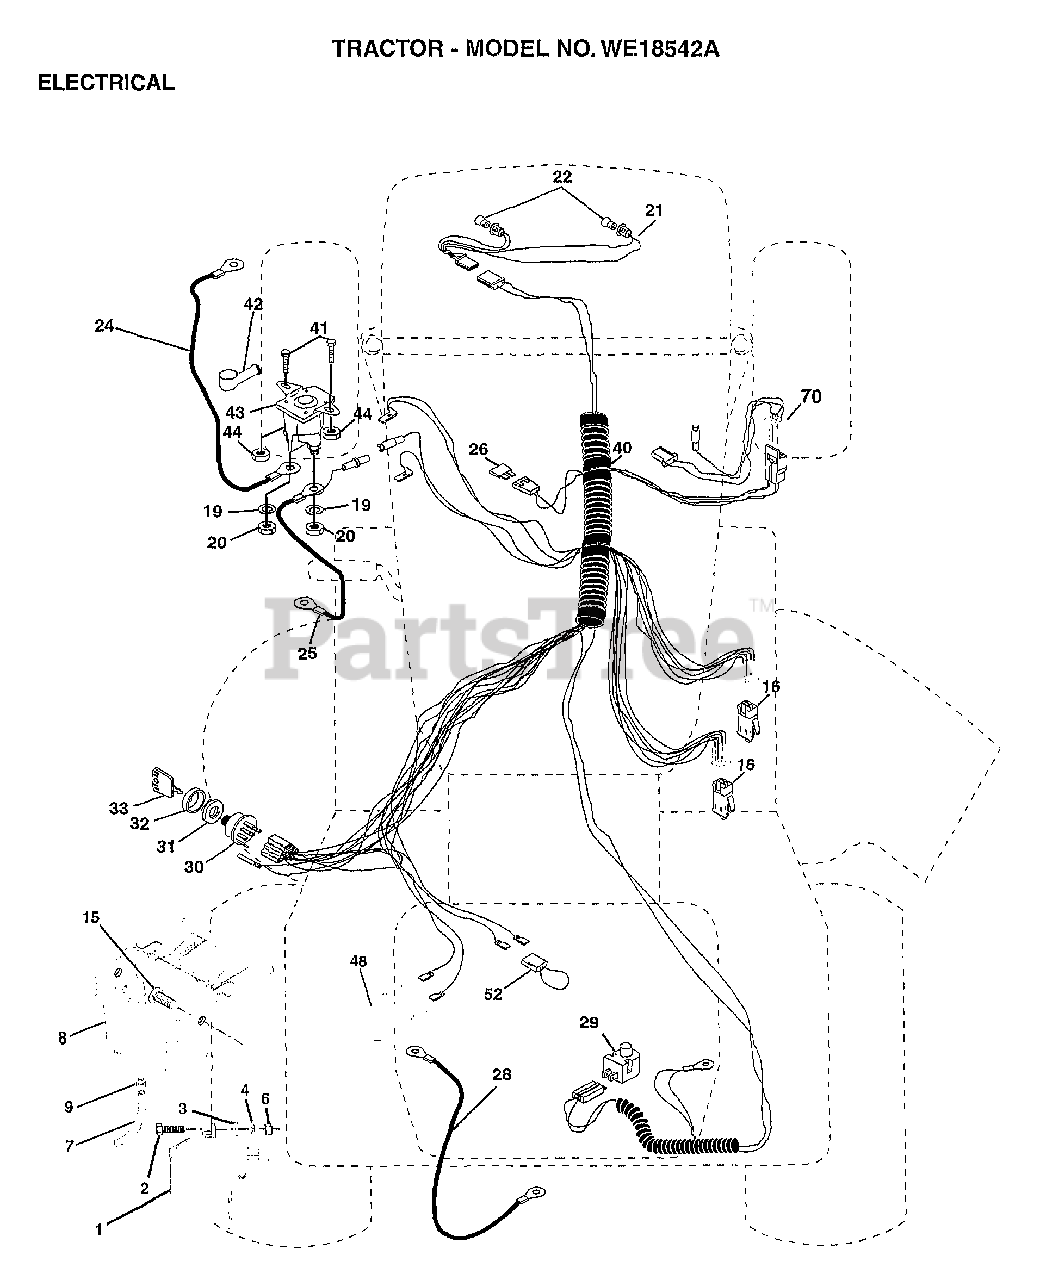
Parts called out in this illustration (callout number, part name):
2	BOLT LT
3	WASHER
4	LOCKWASHER
7	TUBE T
8	"CASE,BATTERY.MECH"
9	HOSE CLAMP T
15	FASTNER.SNAP-IN
16	SWITCH INTERLOCK
20	NUT
21	"HARNESS,LIGHT SOC"
22	HEADLAMP BULB
24	"CABLE T, BATTERY"
25	CABLE.BTRY.6GA.RD
26	FUSE HYT
28	CABLE T
29	SWITCH SEAT
30	SWITCH IGN 4POS
31	NUT IGNITION
32	COVER KEY SWITCH
33	KEY
40	HARNESS-IGNITION
41	BOLT HXHD FIN
44	NUT HXKEP 1/4X20
48	ADAPTER AMMETER
52	PROTECTION LOOP
70	HARNESS ENG DUAL
